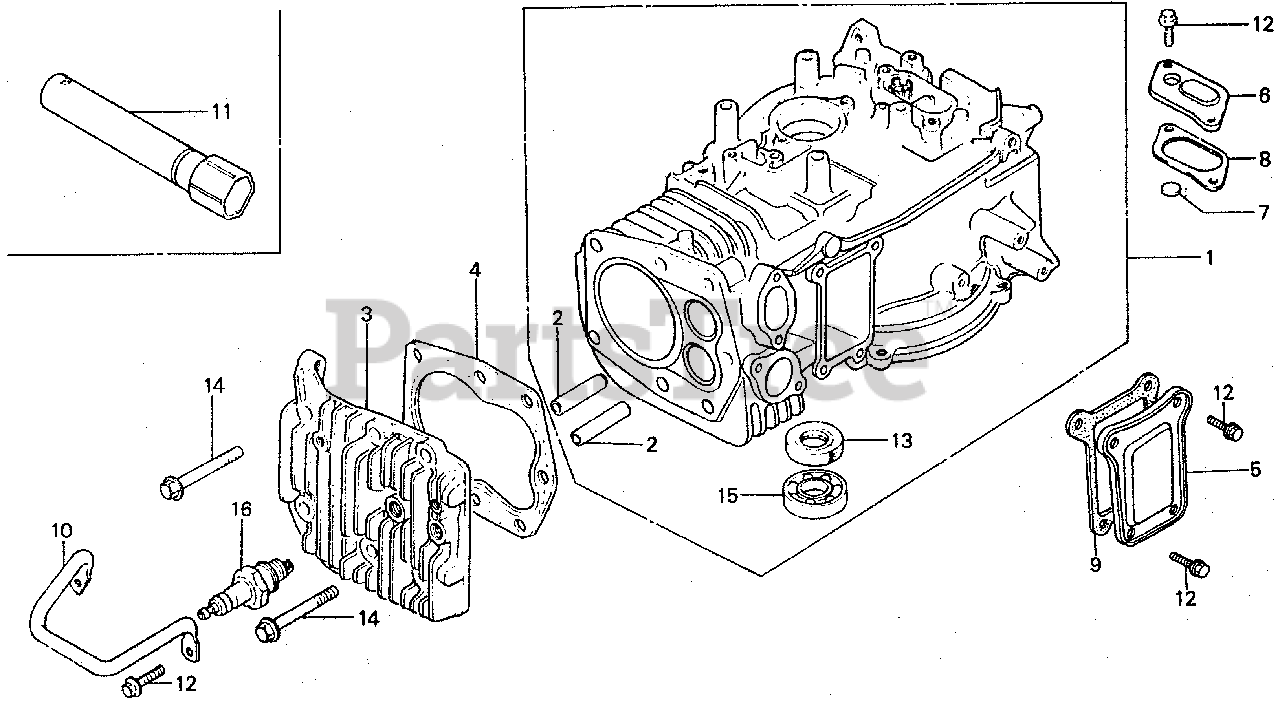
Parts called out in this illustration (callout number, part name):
1	CYLINDER ASSY.
2	GUIDE, VALVE (OVER SIZE)
3	CYLINDER HEAD
4	GASKET, CYLINDER HEAD (NOT AVAILABLE)
5	COVER, TAPPET ROOM
6	CAP, BREATHER CHAMBER
7	VALVE, BREATHER
8	GASKET, BREATHER CAP
9	GASKET, TAPPET COVER
10	GUARD, PLUG
11	WRENCH, SPARK PLUG (NOT AVAILABLE)
12	BOLT, FLANGE (6X12) (CT200)
13	OIL SEAL (25X41X6)
14	BOLT, FLANGE (8X45)
15	BEARING, RADIAL BALL (6205)
16	SPARK PLUG (BM6A) (NGK)
16	SPARK PLUG (W20M-U) (DENSO)
